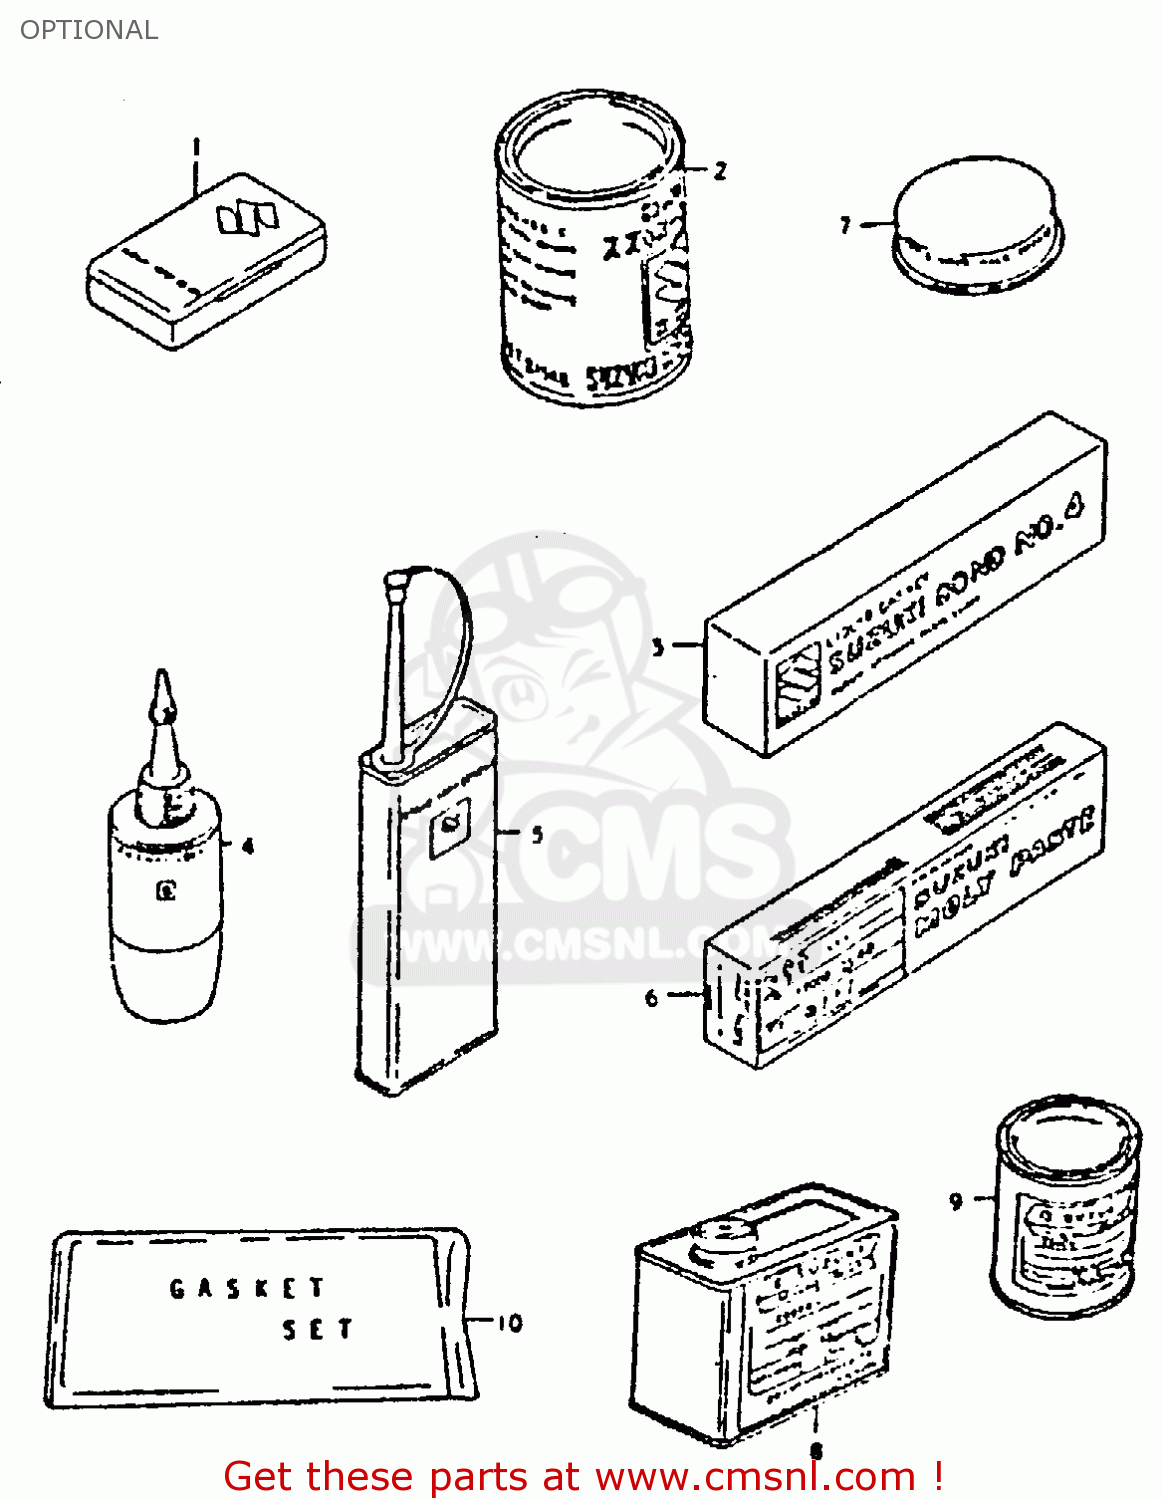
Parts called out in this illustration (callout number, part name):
1	TUBE REPARING TOOL
2	GREASE(C)EP2 LITHIUM 150G
3	BOND 1104
4	THREAD LOCK SUPER (1332B)
5	THREAD LOCK NO.1401 CLEAR 200G
6	SUZUKI MOLY PASTE
7	GREASE,PBC FOR BRK PAD 20G
8	PAINT (BLACK)
9	PAINT,BLACK
10	GASKET SET (MCA)
